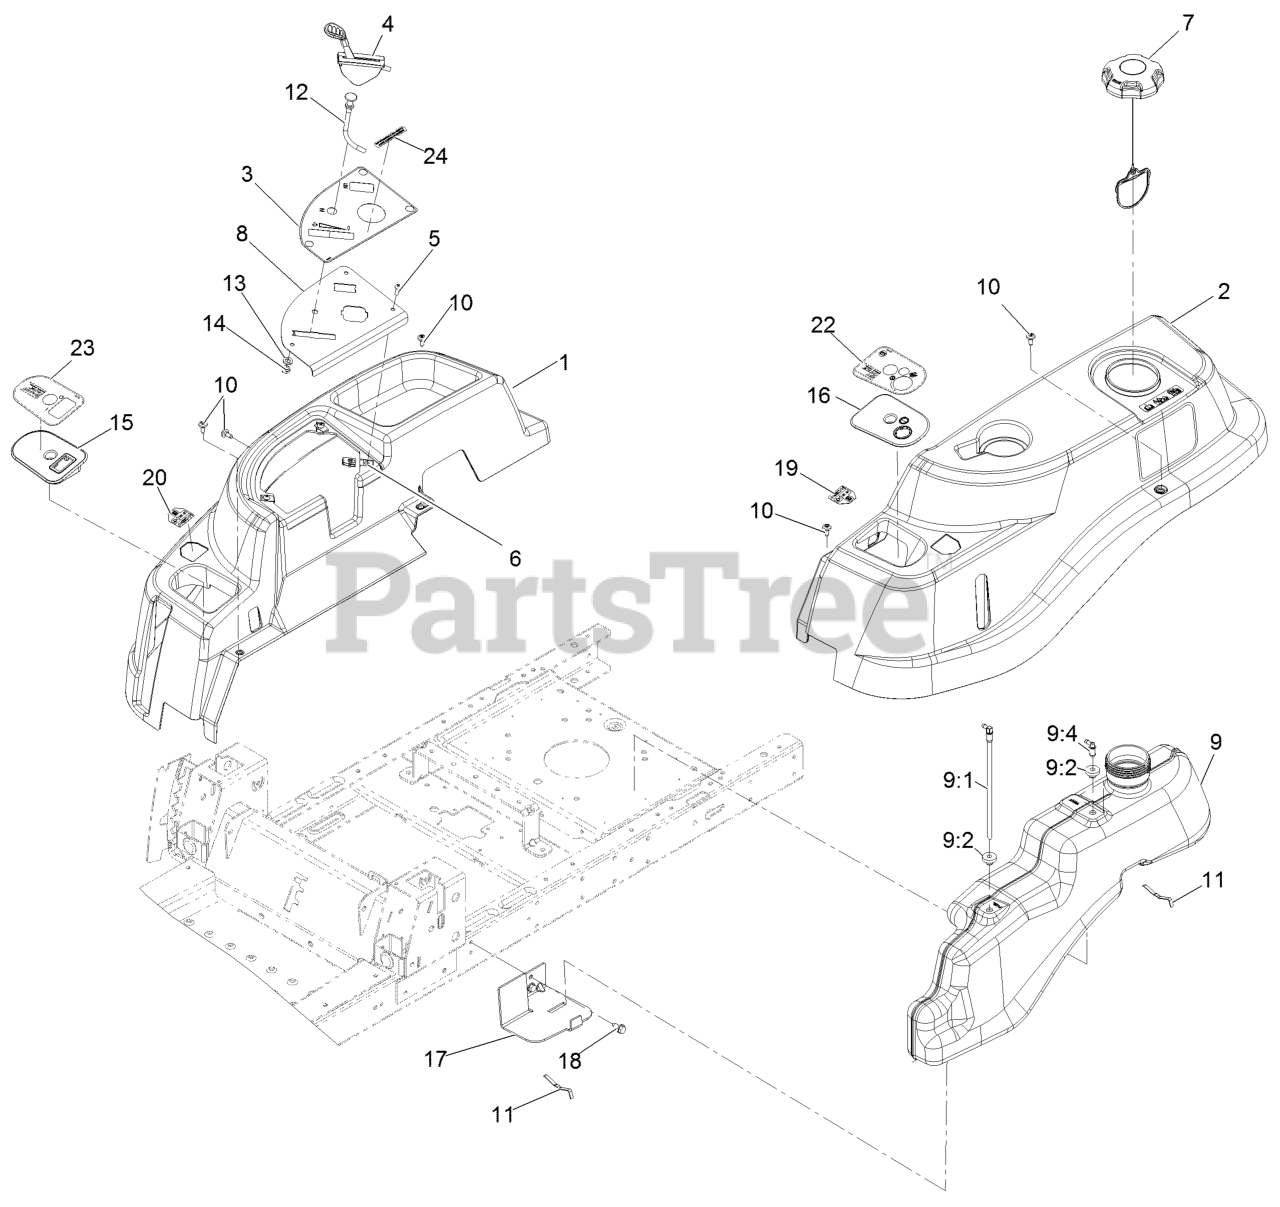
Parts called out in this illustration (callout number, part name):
3	DECAL-PANEL, CONTROL
4	CABLE-THROTTLE
5	SCREW-PRH
6	Nut-Retainer-Panel 1/4-20
8	PLATE-CONTROL
9	FUEL TANK ASM
9:1	CONNECTOR-ELBOW, 90 DEG
9:2	BUSHING
9:4	FITTING-PLASTIC
10	SCREW-SHOULDER
11	SPRING
12	CABLE-CHOKE
13	WASHER-LOCK
14	NUT-HJ
15	COVER-RH
16	COVER-LH
17	SUPPORT-TANK, FRONT
18	Screw-HWH 5/16-18 X 3/4 Tf
19	DECAL-NMIR
20	DECAL-CONTROL, PEDAL
22	DECAL-KEYCHOICE
23	DECAL-BRAKE, PARKING
24	DECAL-SHUTDOWN
